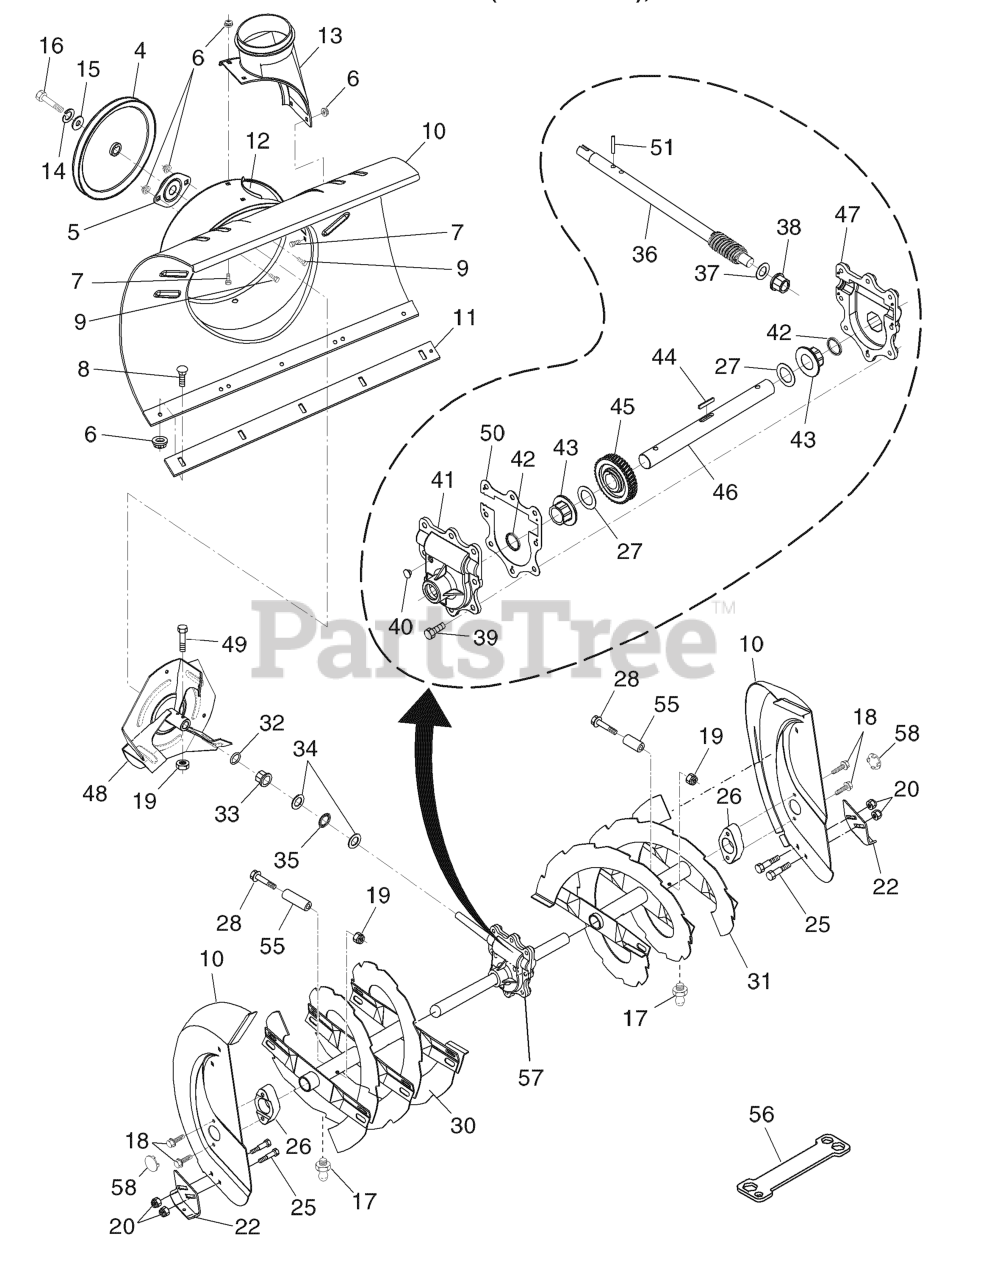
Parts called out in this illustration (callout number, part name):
4	PULLEY, IMPELLER
5	BEARING FLANGE
6	NUT.FLANGE.5/16
7	BOLT.CARRIAGE.5/16-18X
8	BOLT
9	BOLT, HEX HEAD 5/16-18
10	AUGER HOUSING
11	BAR, SCRAPER
12	BRACKET, CORNER DISCHARGE
13	BASE DISCHARGE CHUTE
14	WASHER.LOCK.HVY.HLCL.SPR.5/16
15	WASHER, FLAT
16	CAPSCREW.HX.HD.5/16-18X1.00.NY
17	GREASE FITTING
18	SCREW, HEX HD 5/16X1
19	LOCKNUT.NYLOC.1/4-20
20	NUT.FLANGE.5/16
22	SKID PLATE
25	BOLT
26	BEARING, AUGER
27	WASHER TRUST 1"
28	BOLT, SHEAR
30	AUGER ASSEMBLY, RH
31	AUGER ASSEMBLY, LH
33	BUSHING, FLANGE 3/4
34	WASHER, THRUST 3/4
35	BEARING TRUST 3/4 NTA-1220
36	SHAFT, IMPELLER
37	WASHER, THRUST 5/8
38	FLANGE BUSHING-5/8
39	HEX SCREW-5/16 X 3/4
40	CASE PLUG
41	GEARBOX HOUSING-RH
42	OIL SEAL
43	FLANGE BUSHING-1"
44	KEY, SQUARE 1/4 X .875
45	WORM GEAR
46	AUGER SHAFT
47	HOUSING.GEARBOX.LH(SERVICE)
48	IMPELLER ASSY
49	SCREW.HEX.HD1/4-20X
50	GEARBOX GASKET
51	PIN, ROLL 3/16 X 1-1/8
55	SPACER.3943.SLEEVE.250X.47
56	RP WRENCH, SNOWTHROWER
57	GEARBOX.ASSEMBLY.AUGER
58	PLUG.BEARING.HOLE.HSG
